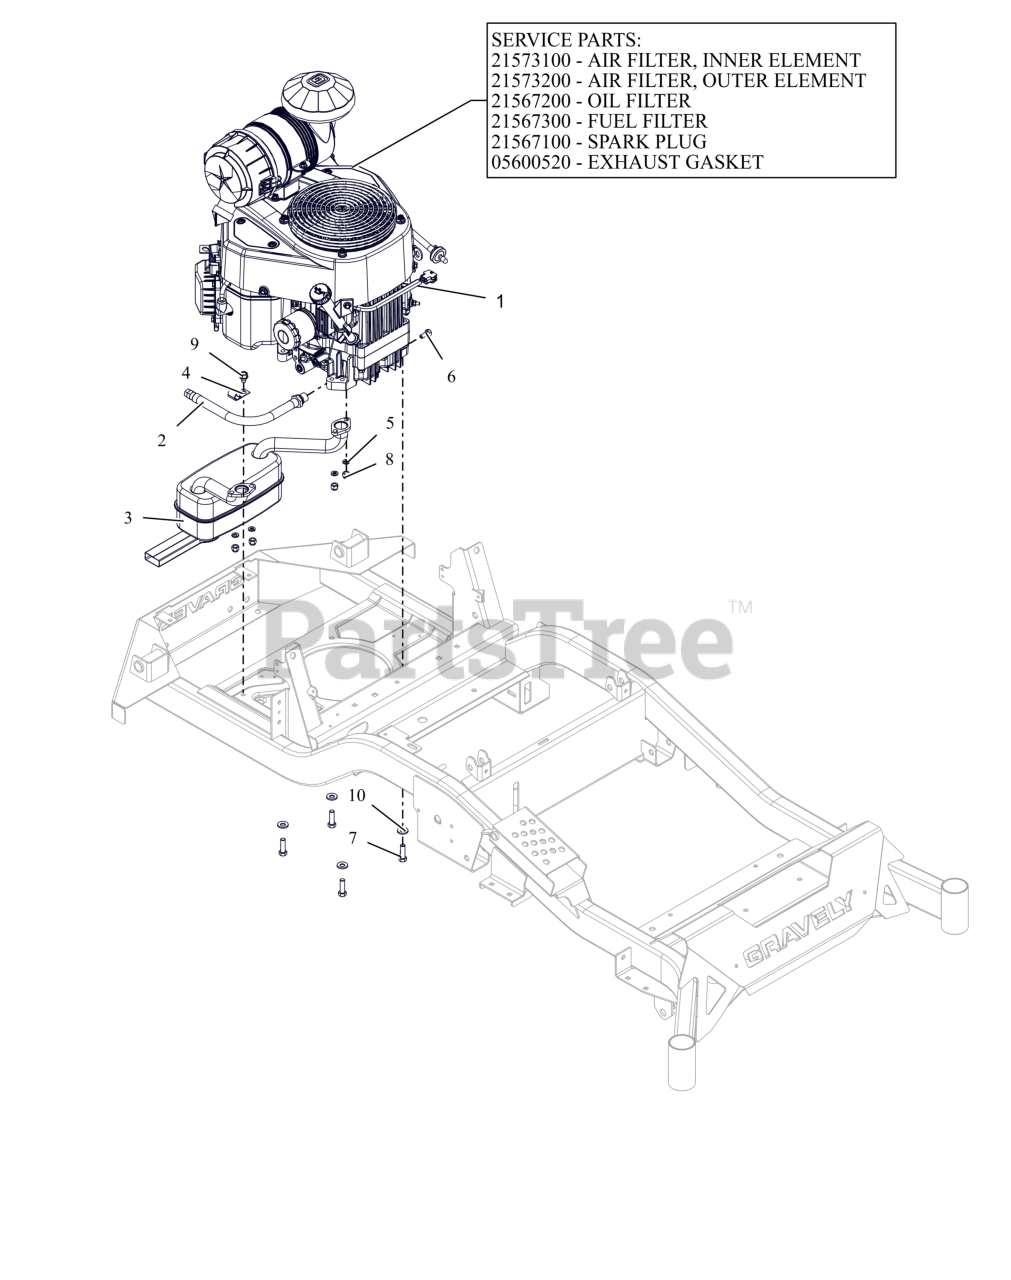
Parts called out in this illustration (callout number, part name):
1	ENGINE, GRAVELY 764CC PRO FILTER
1	FILTER, ELEMENT INNER
1	ELEMENT, AIR FILTER
1	FILTER, OIL LONCIN
1	FILTER, FUEL
1	PLUG, SPARK
1	GASKET, MUFFLER LONCIN
2	HOSE, OIL DRAIN
3	MUFFLER, KAWASAKI
5	WSHR,LK-REG .312X.078 ZCC
6	BLT, HEX M8-1.25X20 G8.8 ZCC
7	BLT, HEX .38-16X1.25 G5 ZCC NT
8	NUT,NYL M8-1.25 G8.8 ZCC
9	SCR,TAP .375-16X.50 HWH TR ZCC
10	WASHER, 3/8" SPRING DISC
